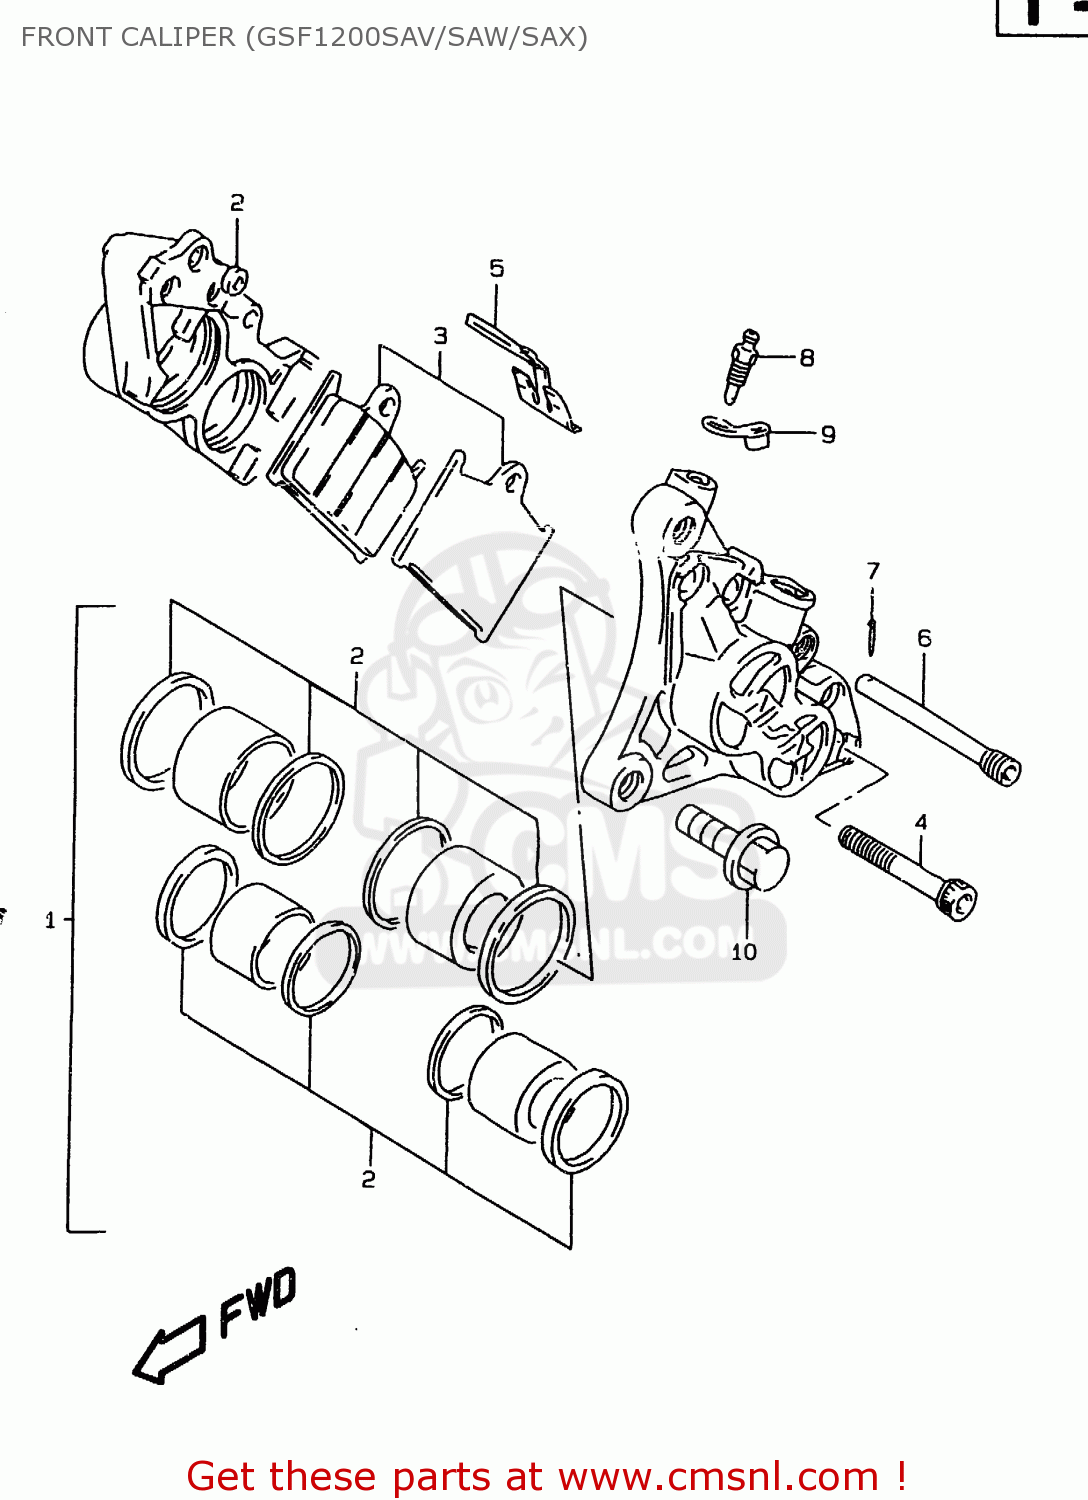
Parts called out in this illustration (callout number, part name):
1	PISTON SET
2	SEAL SET,PISTON
3	PAD SET (NAS)
4	BOLT
5	SPRING
6	PIN,HANGER
7	PIN 16X20
8	BLEEDER
9	CAP,BLEEDER
10	BOLT
